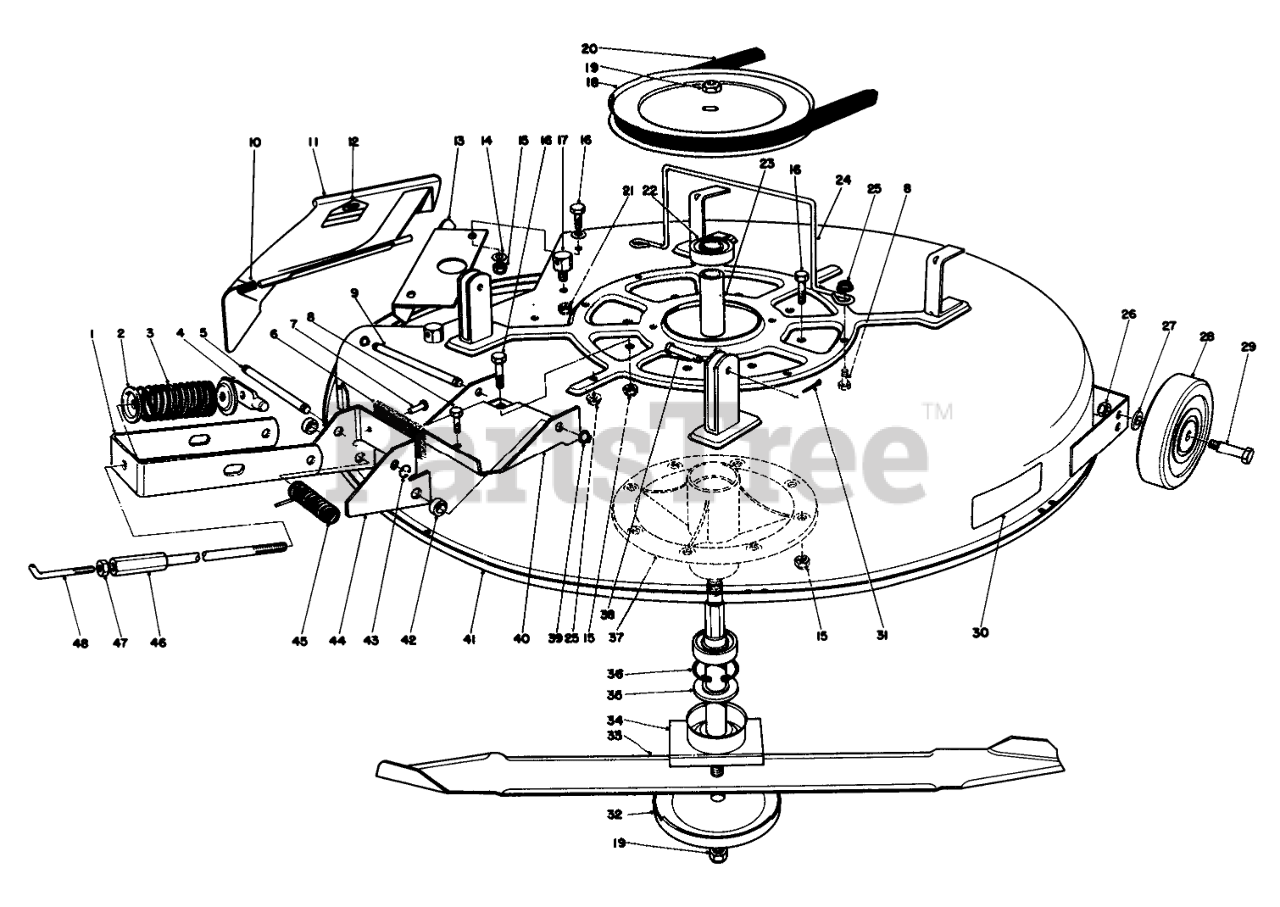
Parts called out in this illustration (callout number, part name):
1	Bracket-Engagement
2	RETAINER-SPR. TOP
3	SPRING-COMPRESSION
4	SHAFT-DECK ADJ.
5	Pin-Clevis
6	Pad-Brake
7	RIVET .187 X 7/16 BRASS
8	SCREW-HH
9	CLEVIS PIN
10	SPRING
11	Deflector Assembly (Incl. Ref. #12)
12	DECAL-DANGER
13	Baffle Deck
14	WASHER-PLAIN
15	NUT-LOCK, NI
16	SCREW-HH
17	POST-PIVOT
18	PULLEY
20	V-BELT, DECK
21	NUT-LOCK, SIDE
22	BEARING-BALL
23	Spacer-Bearing
24	Guide-Belt
25	NUT-LOCK, HHF
26	NUT-LOCK, NI
27	WASHER-FLAT
28	DECK WHEEL
29	BOLT-WHEEL
30	DECK DECAL
31	PIN-COTTER
32	Cup
33	Blade
34	SPINDLE SHAFT WA
35	SPACER-SPINDLE
36	RING-RETAINING
37	SPINDLE
38	PIN-CLEVIS
39	RING-RETAINING
40	DECK ENGAGE CHANNEL R
41	Cutter Deck
42	DECK BRAKE SPACER
43	E-RING
44	Support Deck Brake Assembly (Incl. Ref. #6 & 7)
45	SPRING
46	ADJ HUB WA
47	NUT-JAM
48	ADJ. ROD
